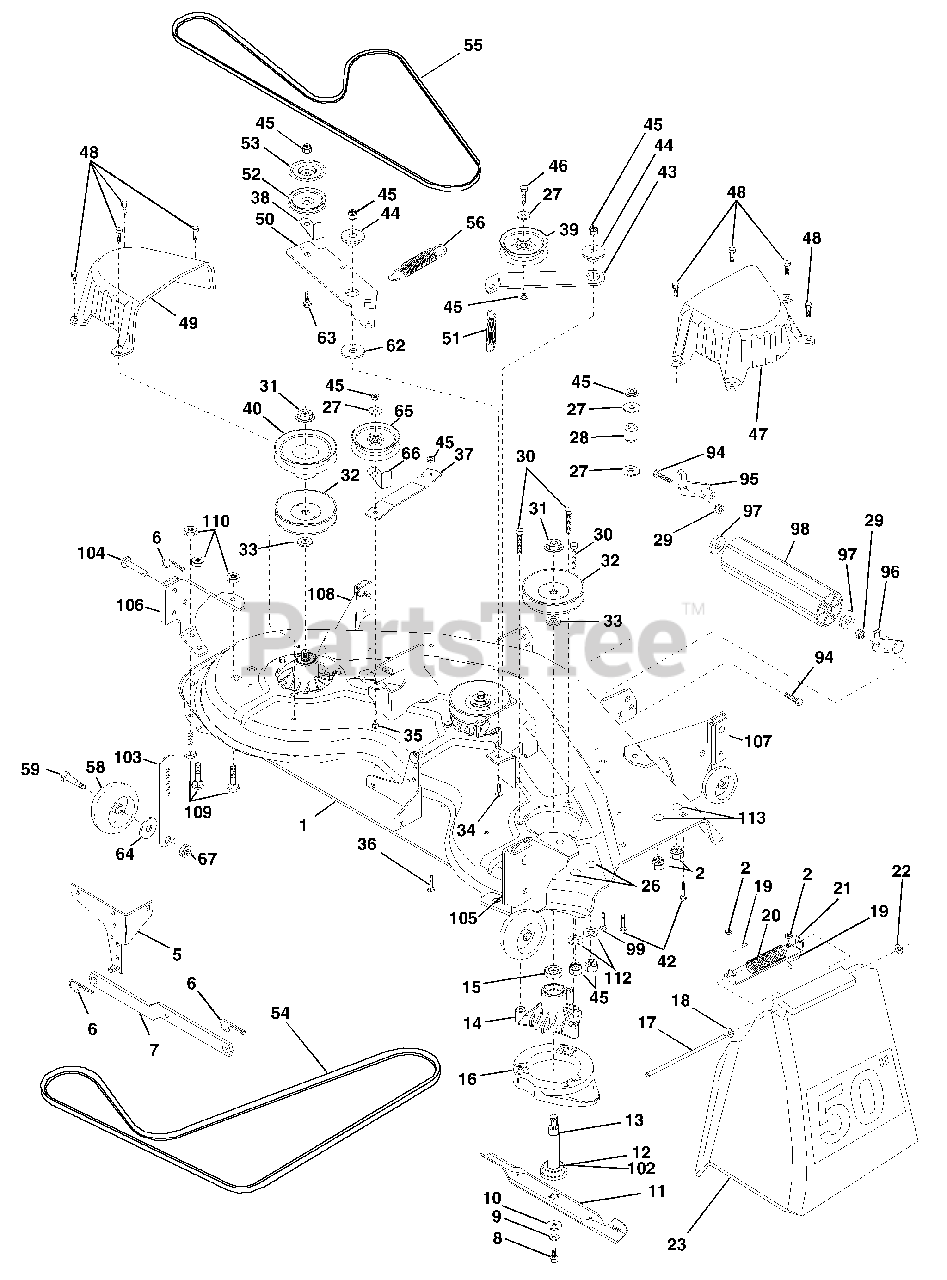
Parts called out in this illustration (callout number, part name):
1	Deck Asm., Mower 50" Vented
2	Nut, Crownlock 5/16-18 Unc
5	Bracket Asm., Sway Bar
6	Retainer, Spring
7	Arm Suspension, Rear
8	Bolt 3/8-24 x 1.25 Gr. 8 Patched
9	Washer, Lock Hvy 3/8 Unplated
10	Washer, Hard Blade Mower Vented
11	Blade (3 Required)
12	Bearing, Ball #6204 (Mandrel)
13	Shaft Asm., W/Lower Brg
14	Housing, Mandrel 50" Vent
15	Bearing, Ball Mandrel
16	Stripper, Mower Vented
17	Rod, Hinge
18	Washer 11/32 x 5/8 x 16 Ga.
19	Cap, Sleeve
20	Spring, Torsion Deflector
21	Bracket, Deflector
23	Shield, Deflector Mower
26	Bolt Rdhd Sht Sqnk 3/8-16 x 3/4
27	Washer 13/32 x 13/16 x 16 Ga.
28	Spacer, Spring Stop Idler
29	Nut, Lock Hex W/Wsh 3/8-16 Unc
30	Screw Tdhrolling Washer Head
31	Nut, Flg Top Lock Cntr 9/16
32	Pulley, Mandrel
33	Washer, Spacer Mower Vented
34	Bolt, Carriage 3/8-16 x 1-1/4
35	Bolt, Carriage 3/8-16 x 2
36	Bolt, Carriage 3/8-16 x 1 Gr. 5
37	Stiffener, Arm Idler
38	Keeper, Belt Idler
39	Pulley, Idler Flat
40	Pulley, Driven
42	Bolt, Carriage 5/16-18 Unc x 3/4
43	Arm, Idler Secondary
44	Spacer, Retainer
45	Nut, Crownlock 3/8-16 Unc
46	Bolt, Fin Hex 3/8-16 Unc x 1-3/4
47	Cover, Mandrel RH
48	Screw, Thd Roll 1/4-20 x 5/8
49	Cover, Mandrel LH
50	Arm, Idler Primary
51	Spring, Secondary
52	Pulley, Idler V Groove
53	Shield, Idler
54	V-Belt, Mower Primary
55	V-Belt, Mower Secondary
56	Spring, Primary
58	Wheel, Gauge
59	Bolt, Shoulder
62	Washer Hardened
63	Bolt Carriage 3/8-16 x 1-1/2
64	Washer 3/8 x 7/8 x 14 Ga.
65	Pulley Idler Flat Mower
66	Keeper, Belt Idler 44/50" Vent
67	Nut, Center Lock 3/8-16
94	Bolt, Fin Hex 3/8-16 UNC x 1
95	Bracket, Asm. Noseroller LH
96	Bracket, Asm. Noseroller RH
97	Washer 17/32 x 7/8 x 16 Ga.
98	Roller, Nose
99	Bolt, Carriage 3/8-16 x 1-3/4 Gr. 5
102	Washer Felt
103	Bar Pnt Adjusting Wheel Gauge
104	Pin Head Rivet
105	Bracket Whl Ga. Asm Rear RH 50"
106	Bracket Whl Ga. Asm. Rear LH 50"
107	Bracket Whl Ga. Asm. Front RH 50"
108	Bracket Whl Ga. Asm Front LH 50"
109	Bolt Carriage 5/16-18 x 5/8 Blk
110	Nut Crownlock 5/16-18 Blk
112	Washer 17/32 x 3/4 x 16 Ga.
113	Bolt Carriage 5/16-UNC x 1/2
